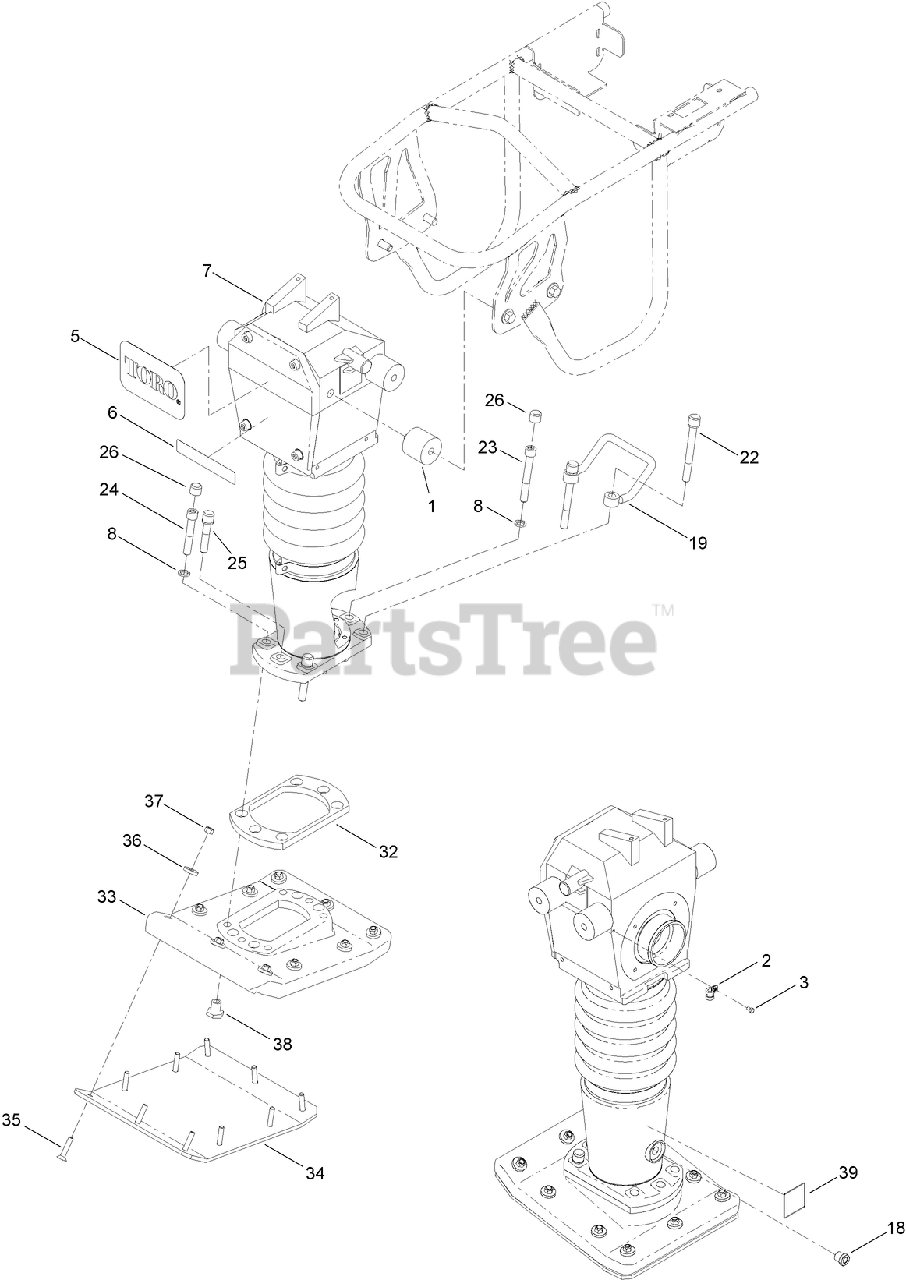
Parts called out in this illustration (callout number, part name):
1	MOUNT-SHOCK
2	CLAMP
3	SCREW-HH
5	DECAL
6	DECAL
7	RAMMER ASM
8	WASHER-LOCK
18	PLUG-SIGHT, OIL
19	GRIP-LIFT
22	SCREW-HSH
23	SCREW-HSH
24	SCREW-HSH
25	SCREW-HSH
26	CAP-PLASTIC
32	PLATE-SPACER, SHOE
33	SHOE-PLASTIC, MEDIUM/HEAVY
34	PLATE-SHOE
35	SCREW-HSFH
36	WASHER-FLAT
37	NUT-LOCK, NI
38	INSERT-SHOE
39	DECAL-OIL LEVEL
